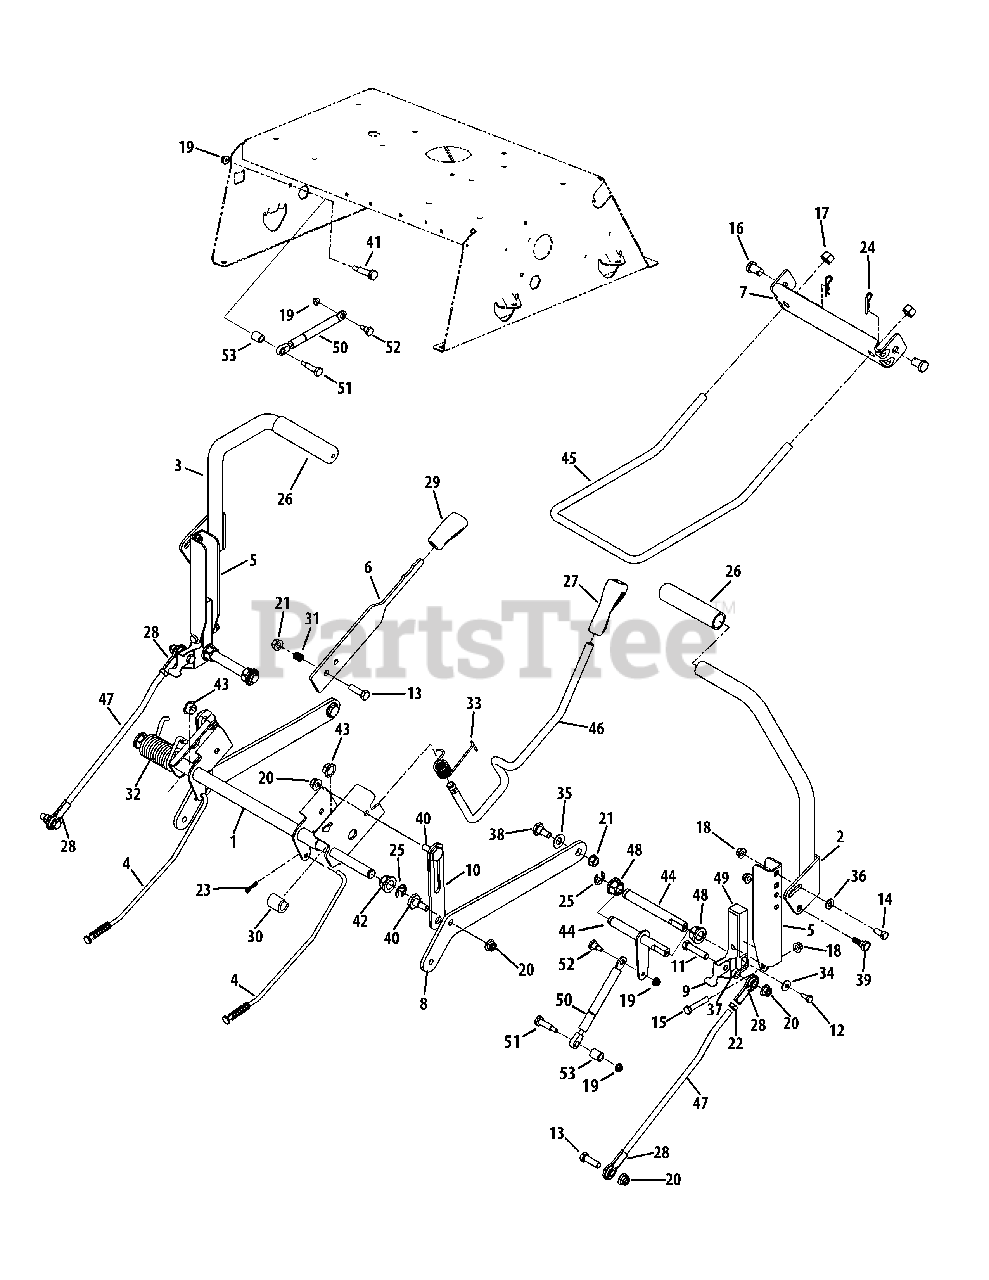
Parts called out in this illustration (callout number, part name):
1	Deck Lift Shift Assembly
2	RH Lapbar Lever Assembly
3	LH Labpar Lever Assembly
4	Brake Rod Assembly
5	Lapbar Pivot Bracket
6	Brake/Shabs Assembly
7	Front Deck Hanger Bracket
8	Deck Lift Arm Plate
9	Switch Actuator Bracket
10	Lift Link Plate
11	Hex Screw, 3/8-16 x 1.75
12	Hex Screw, 1/4-20 x .625
13	Hex Screw, 3/8-16 x 1.25
14	Hex Screw, 5/16-18 x .75
15	Hex Screw, 5/16-18 x 1.75
16	Clevis Pin, .50 x .78
17	Flex Lock Nut, 1/2-13
18	Flange Lock Nut, 5/16-18
19	Flange Lock Nut, 1/4-20 (50" Deck)
20	Flange Lock Nut, 3/8-16
21	Hex Lock Nut, 3/8-16, Centerlock
22	Jam Nut, 3/8
23	Bow-Tie Cotter Pin
24	Cotter Pin, .080 x 1.5625
25	E-Ring
26	Lapbar Grip
27	Handle Grip, 1/2
28	Rod End
29	Selector Handle
30	Spacer, .621 x 1.00
31	Compression Spring, .50 x .50
32	Torsion Spring, 1.191 x 2.78
33	Torsion Spring
34	Bell Washer, .265 x .75 x .062
35	Flat Washer, .510 x 1.00 x .060
36	Flat Washer, .344 x .688 x .065
37	Spacer, .380 x .625 x .265
38	Shoulder Bolt, 3/8-16 x .496 x .336
39	Shoulder Screw, 5/16 x .437 x .268
40	Shoulder Screw, .500 x .434
41	Shldr. Screw, .374 x 1.16 (50" Deck)
42	Hex Flange Bearing
43	Flange Bearing, .626 x .938 x .344
44	Shaft Control
44	Shaft Control, Dampers
45	Front Hanger Deck Lift Rod
46	Deck Lift Handle Rod
47	Lapbar Control Rod
48	Hex Flange Bearing, .629
49	Control Hub
50	Damper Cylinder
51	Shoulder Screw, .374 x 1.16 x 1/4-20
52	Shoulder Screw, .375 x .38 x 1/4-20
53	Spacer, .385 x .630 x .75
